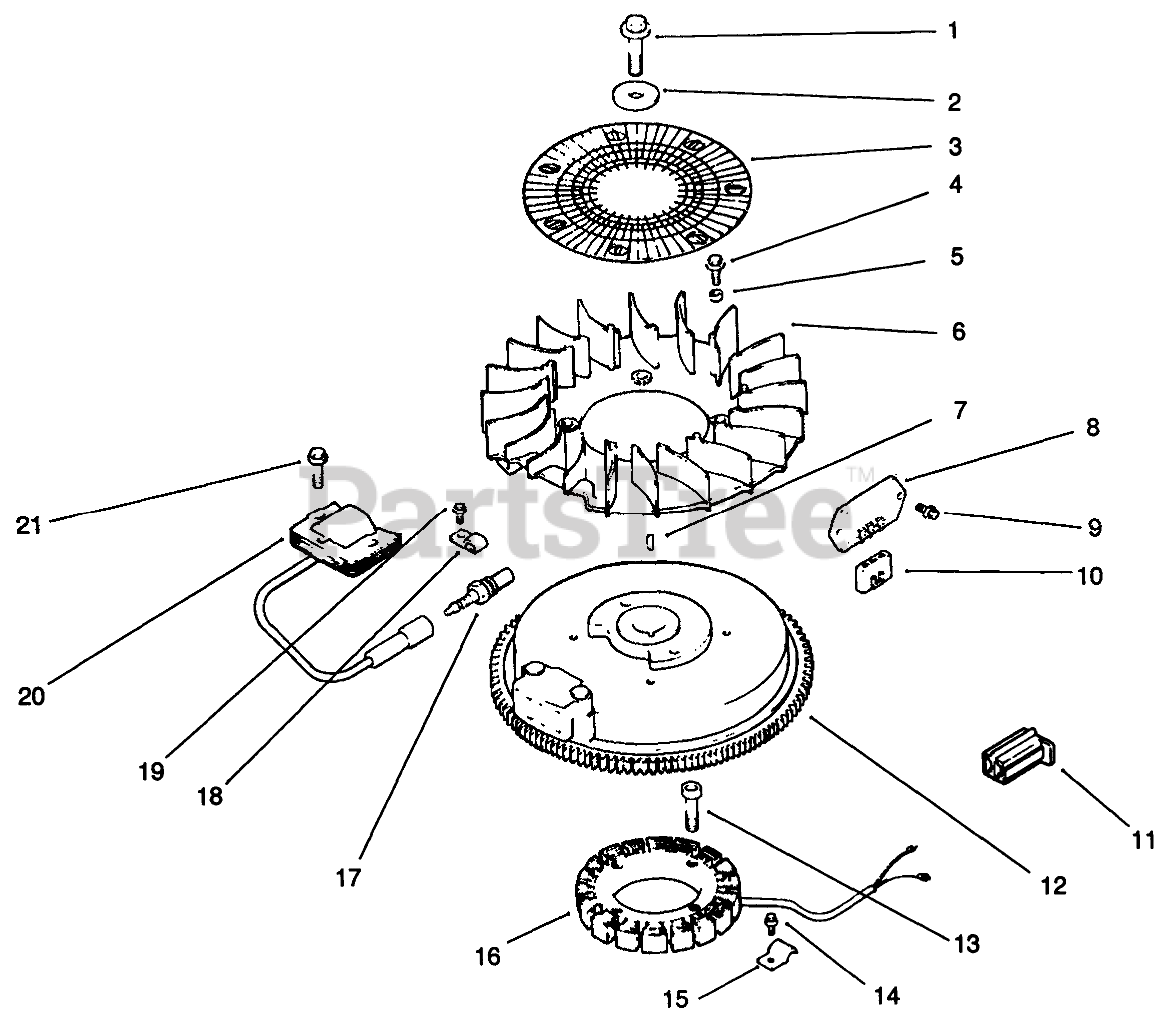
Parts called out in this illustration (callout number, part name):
1	Screw
3	Screen-Grass
4	Screw-Fan
5	Spacer-Fan
6	Fan
7	Key
8	Rectifier-Unregulator
9	Screw
10	Connector
11	Connector
12	Flywheel
13	Screw
15	Clip
16	Stator 15 amp.
17	Spark Plug
18	Clip
20	Module-Ignition
21	Screw
